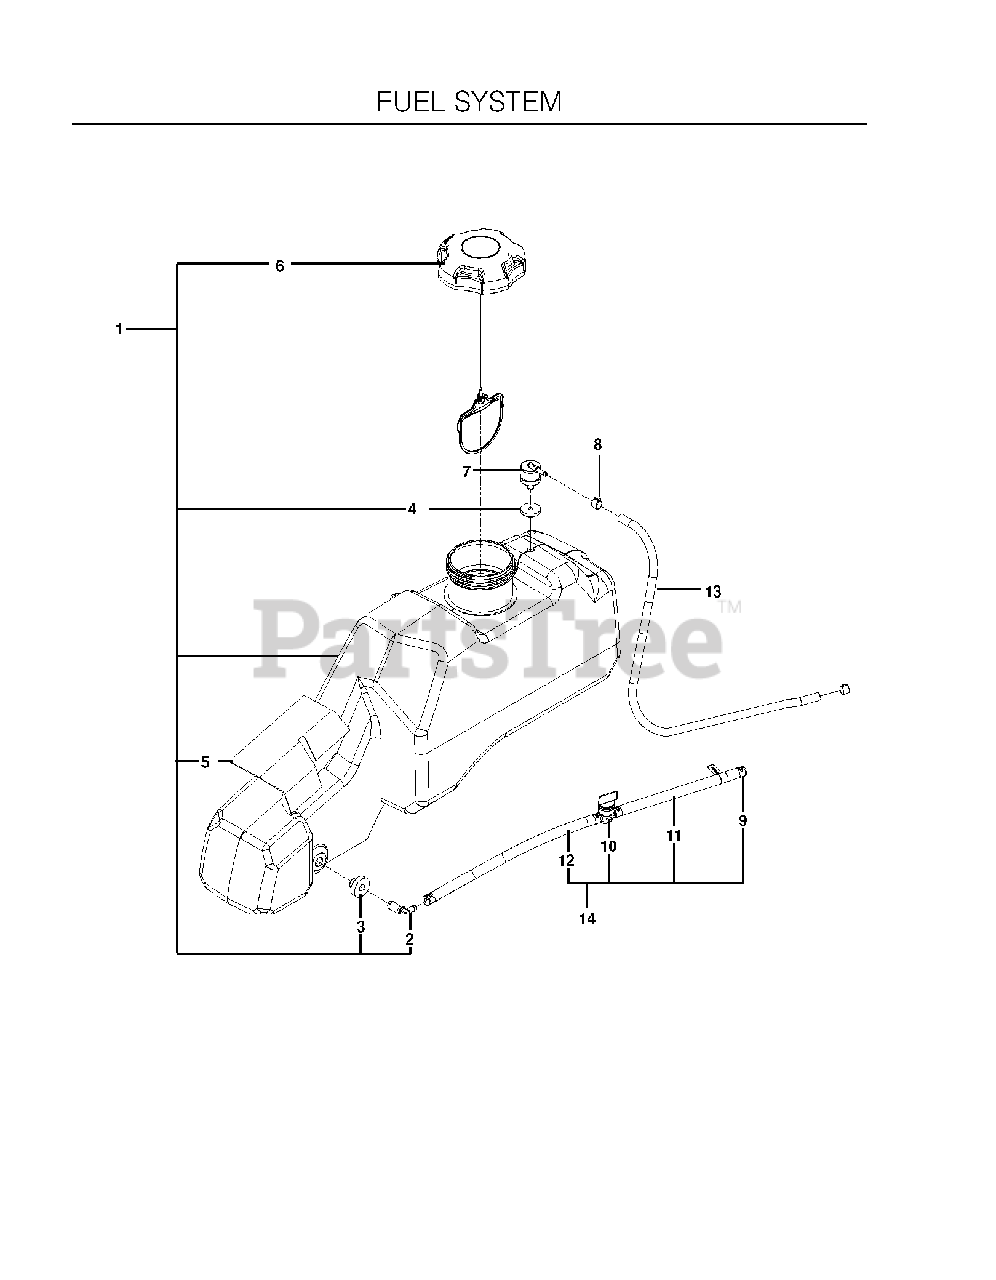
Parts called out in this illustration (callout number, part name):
1	TANK.FUEL.ASSEMBLY.LARGE
2	STEM, FUEL TANK
3	RUBBER GROMMET
4	GROMMET, CHECK VALVE
5	SHIELD, HEAT
6	CAP, FUEL
7	VALVE.FUEL.CHECK
8	CLAMP, HOSE
9	HOSE CLAMP
10	FUEL VALVE
11	GAS LINE 10"
12	FUEL LINE 14"
13	HOSE, VAPOR 3/16 X 48"
14	ASSEMBLY, FUEL LINE, KAW
